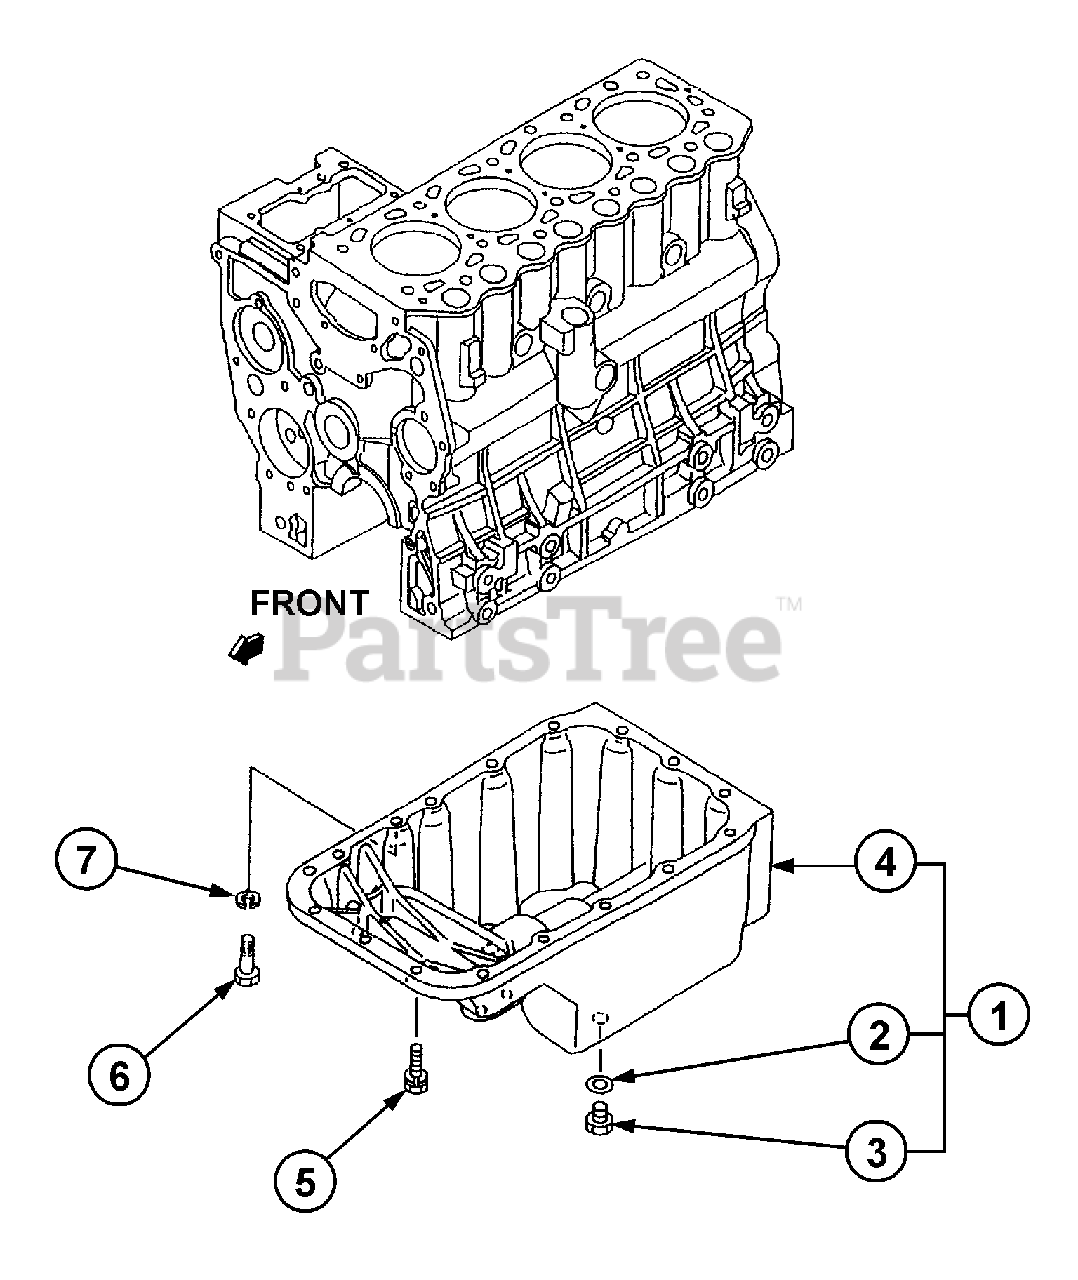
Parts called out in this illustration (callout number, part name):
1	Pan Assy, Oil
4	Pan, Oil
5	Bolt, w/Washer
7	Washer, Spring
